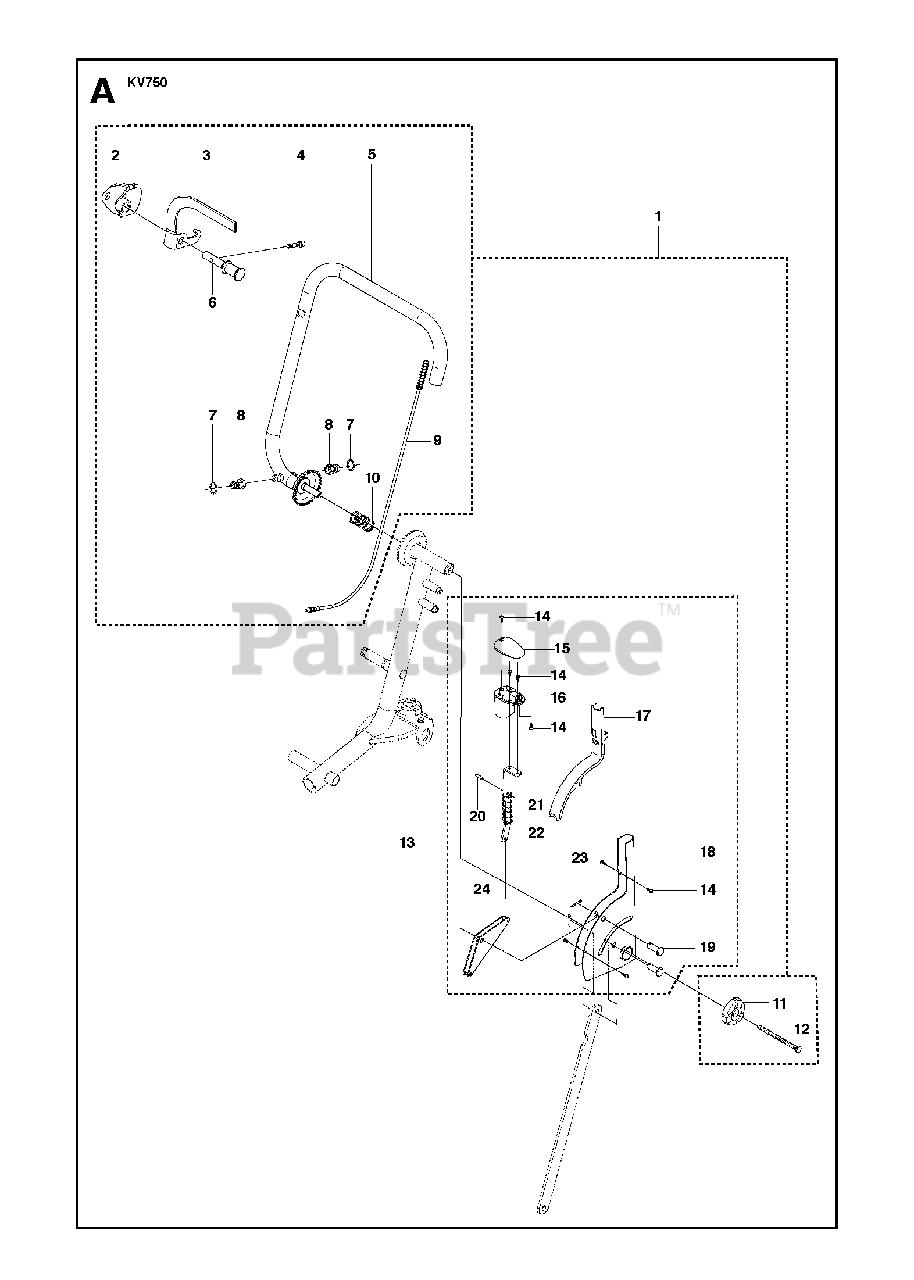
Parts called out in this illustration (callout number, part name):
1	HANDLEBAR ASSYIncl. 2 - 12
3	THROTTLE HANDLE ASSY
10	SPRING THROTTLE CONTROL
11	TURNING KNOB
14	SCREW CRPANT
